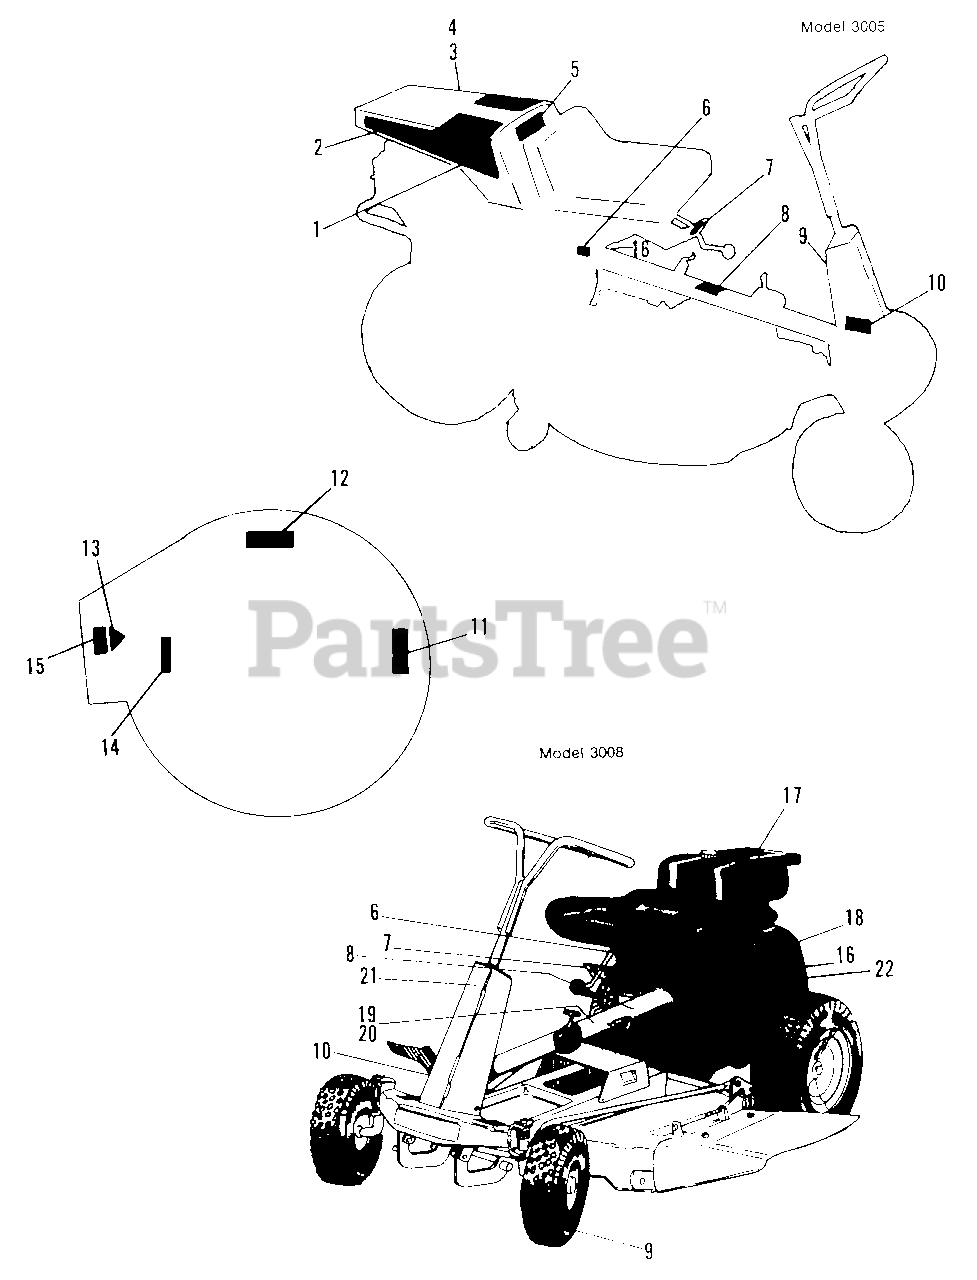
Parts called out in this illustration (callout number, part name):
1	FILM, 3005, R.H.
2	FILM, 3005, R.H. Insert
3	FILM, 3005, L.H.
4	FILM, 3005, R.H., Insert
5	DECAL, Safety
6	FILM, Switch
7	FILM, Shift Pattern
8	FILM, Parking Brake
9	FILM, Tire Inflation
10	FILM, Instruction, Pedal
11	DECAL, Caution
12	TRANSFER, Patent
13	DECAL, OPEI
14	DECAL, Safety
15	DECAL, Danger
16	FILM, Clutch
17	FILM, Caution
18	FILM, Safety
19	FILM, 3008, Insert
20	FILM, 3008
21	DECAL, S
